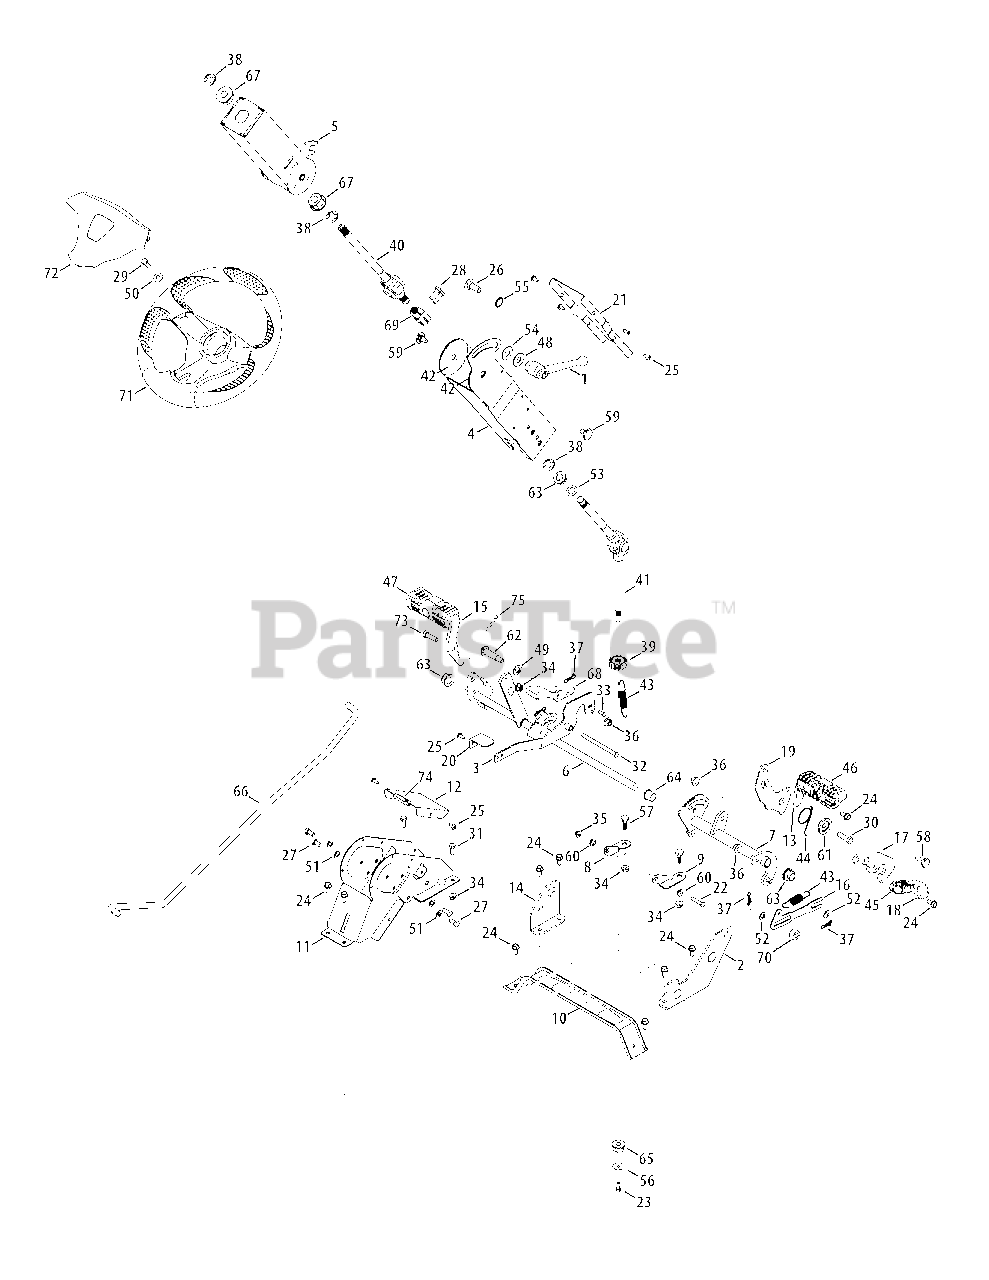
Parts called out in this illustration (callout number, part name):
1	Steering Column Adjustment Lever
2	Support Bracket Assembly, RH
3	Brake Pedal Assembly
4	Lower Column Assembly
5	Upper Column Assembly
6	Brake Pedal Assembly
7	Drive Pedal Assembly
8	Speed Bracket, LH
9	Speed Bracket, RH
10	Steering Support Bracket
11	Lower Steering Wheel Column
12	Lower Column Cover
13	Drive Pedal
14	Support Bracket, LH
15	Brake Pedal
16	Return to Neutral Link
17	Reverse Pedal Bracket
18	Reverse Pedal
19	Forward pedal Bracket
20	Tilt Steering Pedal
21	Steering Column Cover
22	Hex Head Screw, 1/4-20 x 1.25
23	Hex Head Screw, 1/4-20 x .625
24	Hex Washer Screw, 5/16-18 x .750
25	Screw, 1/4-20 x .5
26	Carriage Bolt, 1/2-13 x 1.25
27	Hex Screw, 5/16-18 x .625
28	Hex Cap Screw, 5/16-18 x 1.00
29	Hex Screw, 5/16-24 x.875
30	Hex Screw, 3/8-16 x 1.25
31	Hex Screw, 5/16-18 x .75
32	Clevis Pin, 5/16 x 4.135
33	Clevis Pin, .224 Dia. x .625
34	Flange Lock Nut, 5/16-18
35	Flange Lock Nut, 1/4-20
36	Flange Lock Nut, 3/8-16
37	Bow-Tie Cotter Pin, 72
38	E-Ring, .750
39	14-Tooth Spur Gear
40	Upper Steering Shaft
41	Lower Steering Shaft
42	Column Wear Plate
43	Extension Spring, .70 OD x 3.035 LG
44	Torsion Spring, 1.00 ID x .22
45	Reverse Pedal Pad
46	Forward Pedal Pad
47	Brake Pedal Pad
48	Washer, Flat, .531 x 1.25 x .100
49	Flat Washer, .535 x .930 x .090
50	Bell Washer, .340 x .872 x .060
51	Flat Washer, .330 x .630 x .064
52	Thrust Washer, .375 x .700 x .030
53	Flat Washer, .634 x 1.00 x .040
54	Washer, .640 x 1.25 x .050
55	Lock Washer, 17 x 23.8 x 1.95
56	Flat Washer, .265 x 1.00 x .030
57	Shoulder Screw, 5/16-18 x .437 x .268
58	Shoulder Bolt, 3/8-16 x .500 x .270
59	Shoulder Screw, 3/8-16 x .625 x .175
60	Shoulder Spacer, .375 x .625 x .20
61	Shoulder Spacer, 1.50 x .38 x .38
62	Shoulder Screw, 3/8-16 x .496 x 1.445
63	Hex Flange Bearing
64	Flange Bearing, .63 ID x .695 OD x .06
65	Hex Flange Bearing, 7/16
66	Front Brake Rod
67	Flange Bearing, .63 ID x 1.50
68	Cruise Latch
69	Steering Shaft Coupling
70	Spacer, .385 ID x .875 OD x .458
71	Steering Wheel Assembly
72	Steering Wheel Cover
73	Hex Cap Screw, 5/16-18 x 1.00
74	Trim Strip
75	Cotter Pin, 5/32 x 1.25
